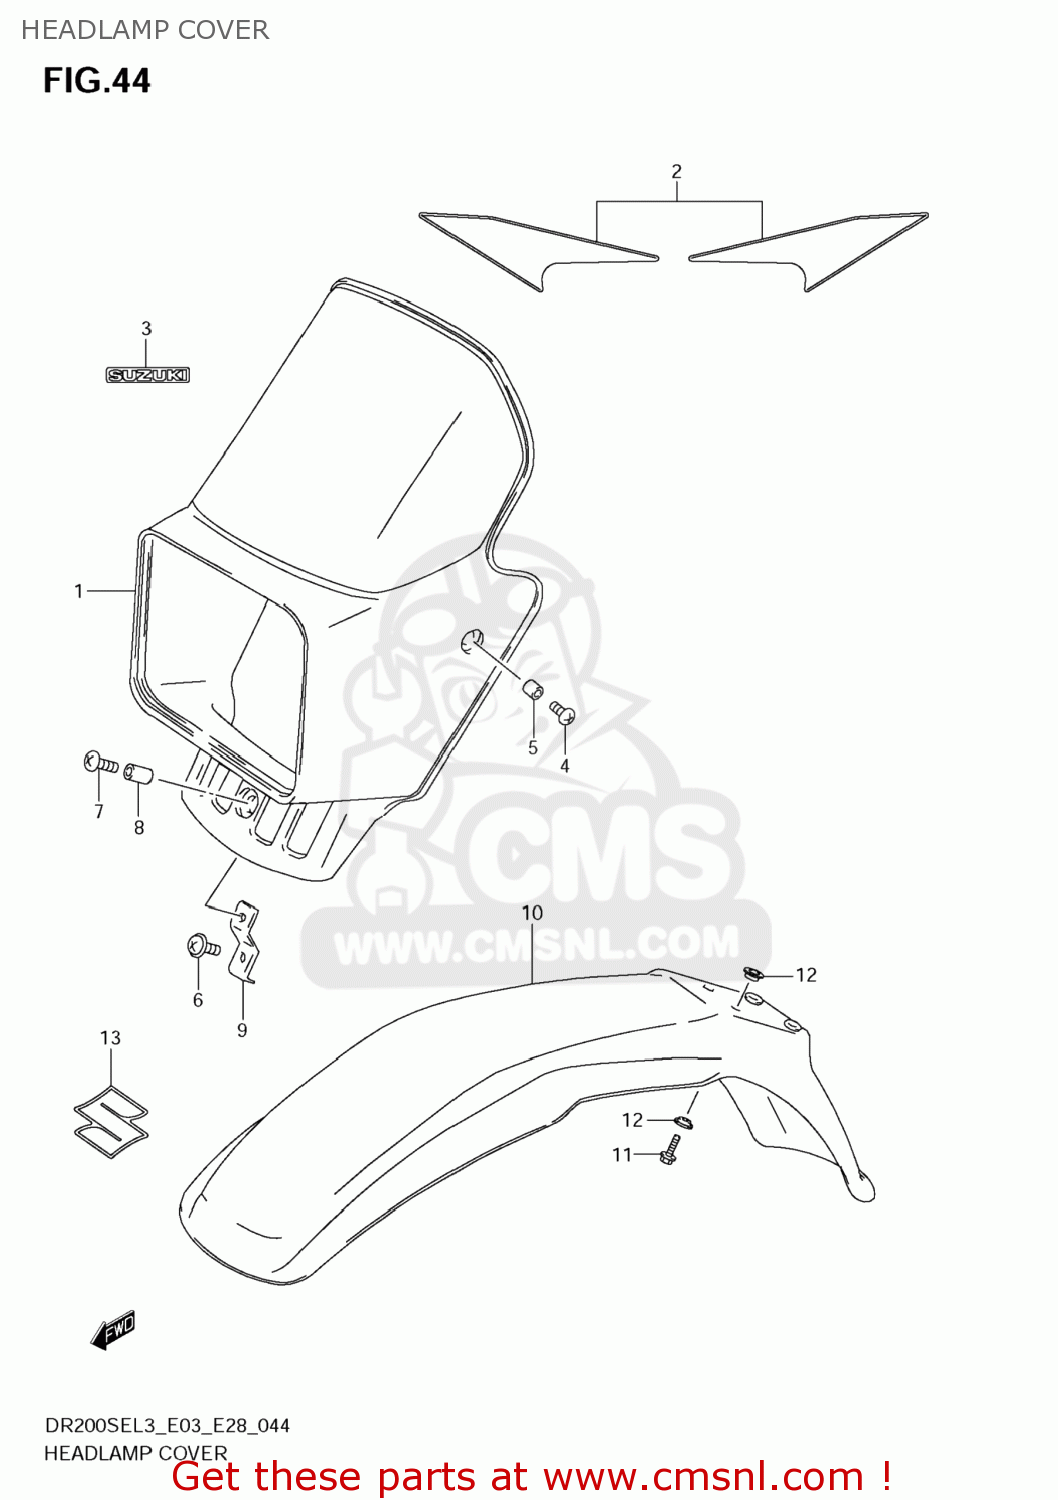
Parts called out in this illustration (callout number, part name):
1	COVER,HEADLAMP
2	TAPE SET,HEADLAMP COVER
3	EMBLEM,SUZUKI
4	SCREW
5	SPACER(6.1X8X3.5)
6	SCREW
7	SCREW
8	SPACER(6.1X8X12)
9	BRACE,HEADLAMP HOUSING LWR
10	FENDER,FR
11	BOLT
12	WASHER
13	EMBLEM,S
